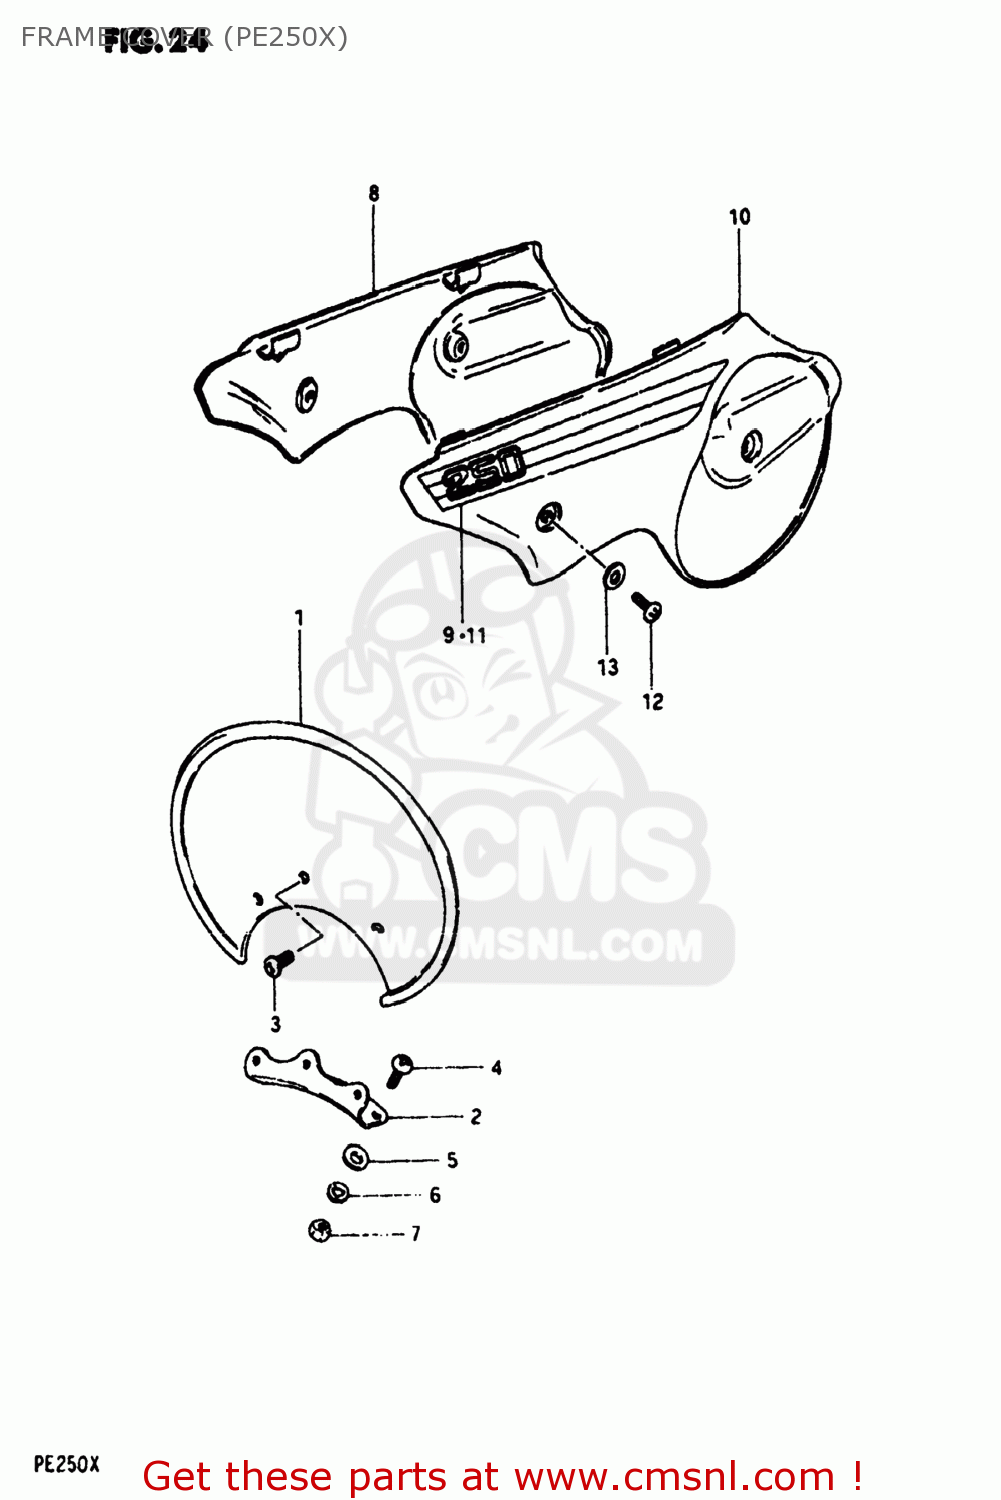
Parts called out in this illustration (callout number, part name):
1	PLATE,NUMBER,FRONT
2	BRACKET FR NUM PLATE
3	SCREW
4	SCREW
5	WASHER
6	LOCK WASHER
7	NUT
8	COVER,FRAME,R(YELLOW)
9	TAPE,FRAME COVER
10	COVER,FRAME,L(YELLOW)
11	TAPE,FRAME COVER
12	SCREW
13	SPACER
